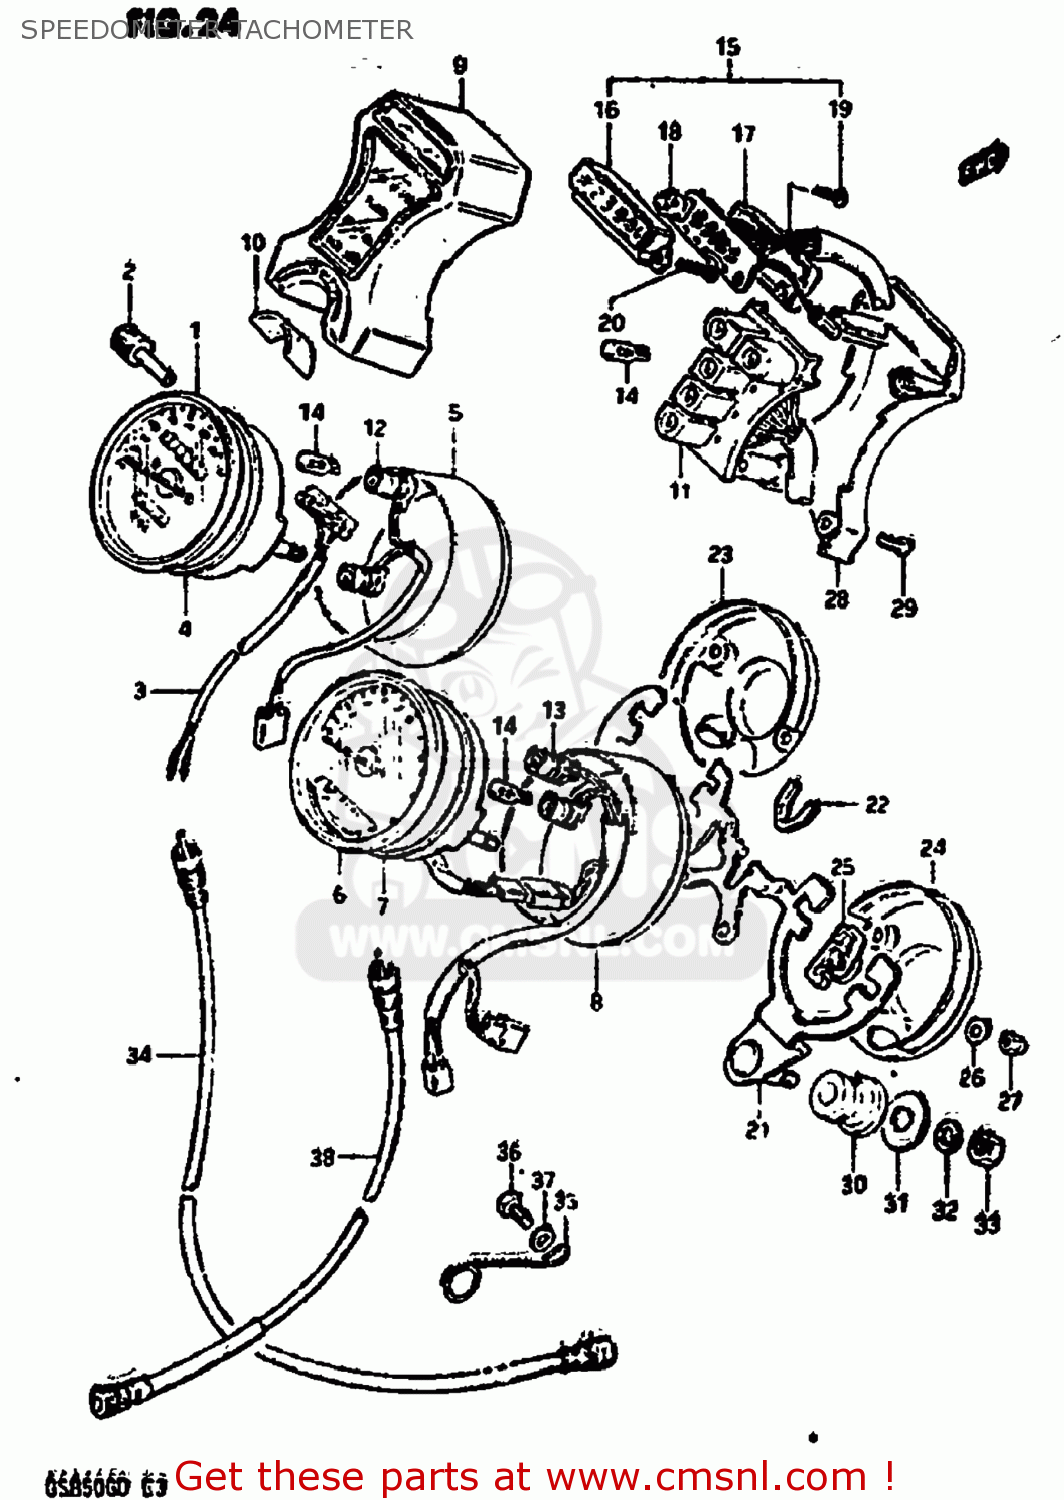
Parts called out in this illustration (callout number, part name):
1	SPEEDOMETER ASSEMBLY
2	KNOB,TRIP
3	WIRE,LEAD
4	CUSHION,METER
5	COVER,SPEEDOMETER
6	TACHOMETER
7	CUSHION,METER
8	COVER,TACHOMETER
9	CASE,PILOT BOX
10	SEAL,IGNITION SWITCH
11	SOCKET,PILOT BOX
12	SOCKET,SPEEDOMETER
13	SOCKET,TACHOMETER
14	BULB(12V3.4W,T10)
15	INDICATOR ASSEMBLY,GEAR POSITION
16	CASE,GEAR INDICATOR
17	COVER,LWR
18	BULB(14V1.12W)
19	SCREW,GEAR INDICATOR
20	SCREW
21	BRACKET,COMBINATION METER
22	BRACKET,COVER
23	COVER,METER,UNDER
24	COVER,TACHOMETER,UNDER
25	CUSHION
26	WASHER
27	NUT
28	COVER,PILOT BOX LWR
29	SCREW,PILOT BULB CASE
30	CUSHION,METER BRACKET
31	WASHER (8.5X29X1.6)
32	LOCK WASHER
33	NUT
34	CABLE ASSEMBLY,SPEEDOMETER
35	CLAMP,SPEEDOMETER CABLE
36	BOLT, UPPER
37	WASHER
38	CABLE ASSEMBLY,TACHOMETER
